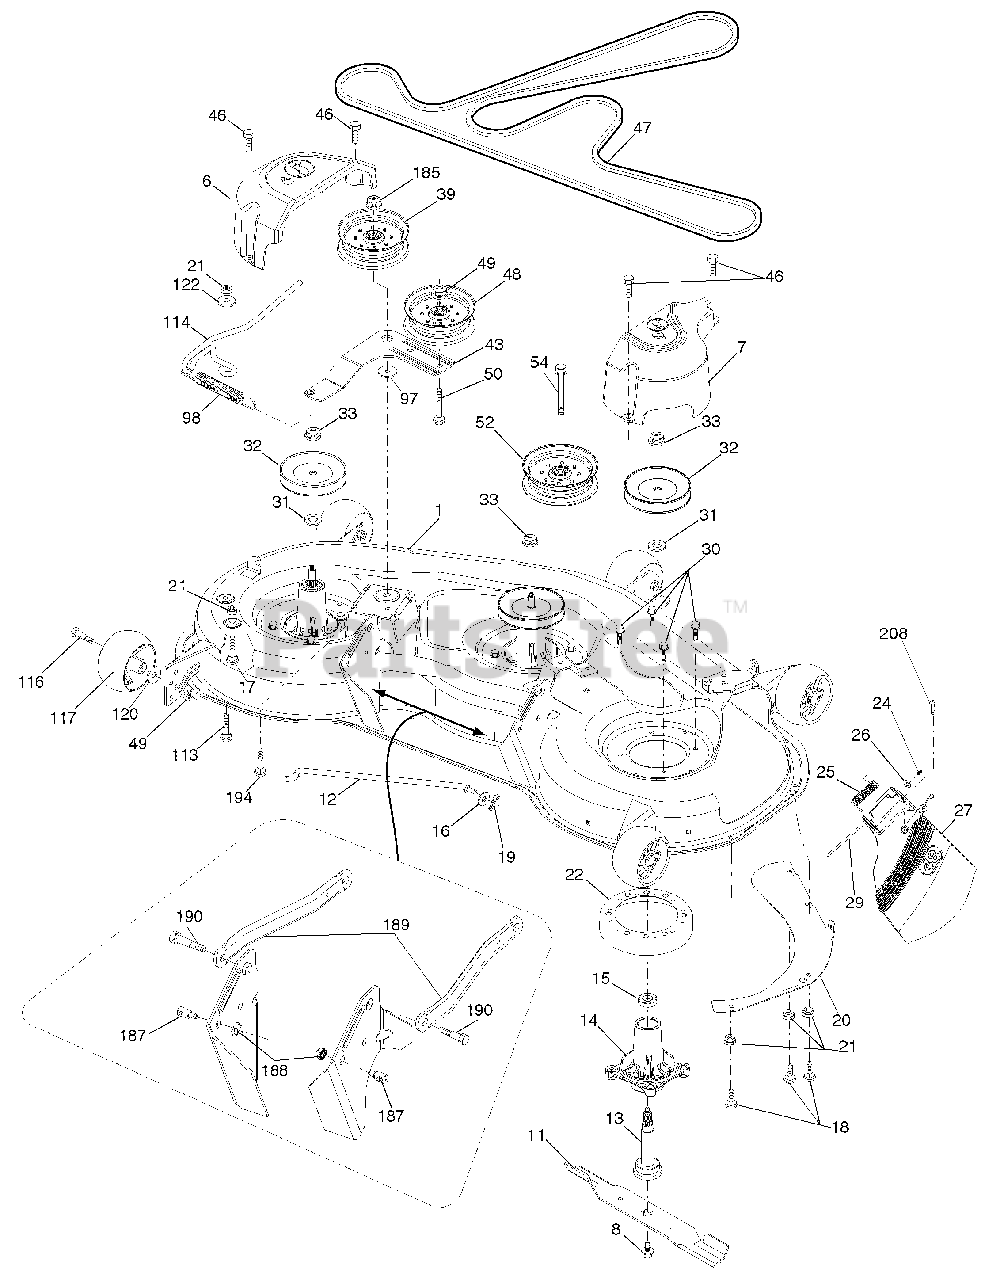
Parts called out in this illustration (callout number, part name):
1	Deck Weldment Mower
6	Cover Mandrel LH
7	Cover Mandrel RH
8	Bolt 7/16 Asm. Blade
11	Blade High Lift
11	Blade Mulching
12	Rod Anti Sway
13	Shaft Asm. w/Lower Bearing
14	Housing, Mandrel
15	Bearing, Ball, Mandrel
16	Washer 13/32 x 13/16 x 12 Ga.
17	Bolt 5/16-18 x 5/8
18	Bolt RdHd 5/16-18 unc x 5/8
19	Pin Cotter 5/16 Bow Tie Lock
20	Baffle Vortex
21	Nut, Crownlock 5/16-18 unc
22	Stripper Mandrel
24	Cap Sleeve
25	Spring, Torsion
27	Deflector Shield
29	Rod, Hinge
30	Screw, Thdroll Washer Head
31	Washer, Spacer Mower Vented
32	Pulley, Mandrel
33	Nut, Flg. Top Lock
39	Pulley, Idler, 4.50 HUB
43	Arm, Idler
46	Screw, Thdroll. 1/4-20 x 5/8
47	Belt Deck Drive
48	Pulley Idler Primary
49	Nut, Lock Flg. 3/8-16 unc
50	Screw TT 3/8-16 x 2-1/4
52	Pulley Idler 4.50 RAW
54	Bolt Carr. Sh 3/8-16 x 1-1/2 Gr. 5
97	Washer Hardened
98	Spring Drive
113	Bolt Rdhd Sqnk 5/16-18 x 3/4
114	Rod Tension Relief
116	Bolt, Shoulder
117	Gauge Wheel
120	Washer 13/32 x 1-1/4 x 12 Ga.
122	Bushing Tension Relief
185	Nut Lock Flange 7/16-14 Gr. 5
187	Stud Fastener w/"D" Anti-Rotation
188	Nut Lock Hex Flange
189	Arm Susp. Mower Rear
190	Bolt Shoulder
194	Bolt Carr Sqnk 7/16-24 x 2
208	Screw Thdrol 3/8-16 x 1/2
208	Mandrel Assembly
208	Replacement Mower, Complete
